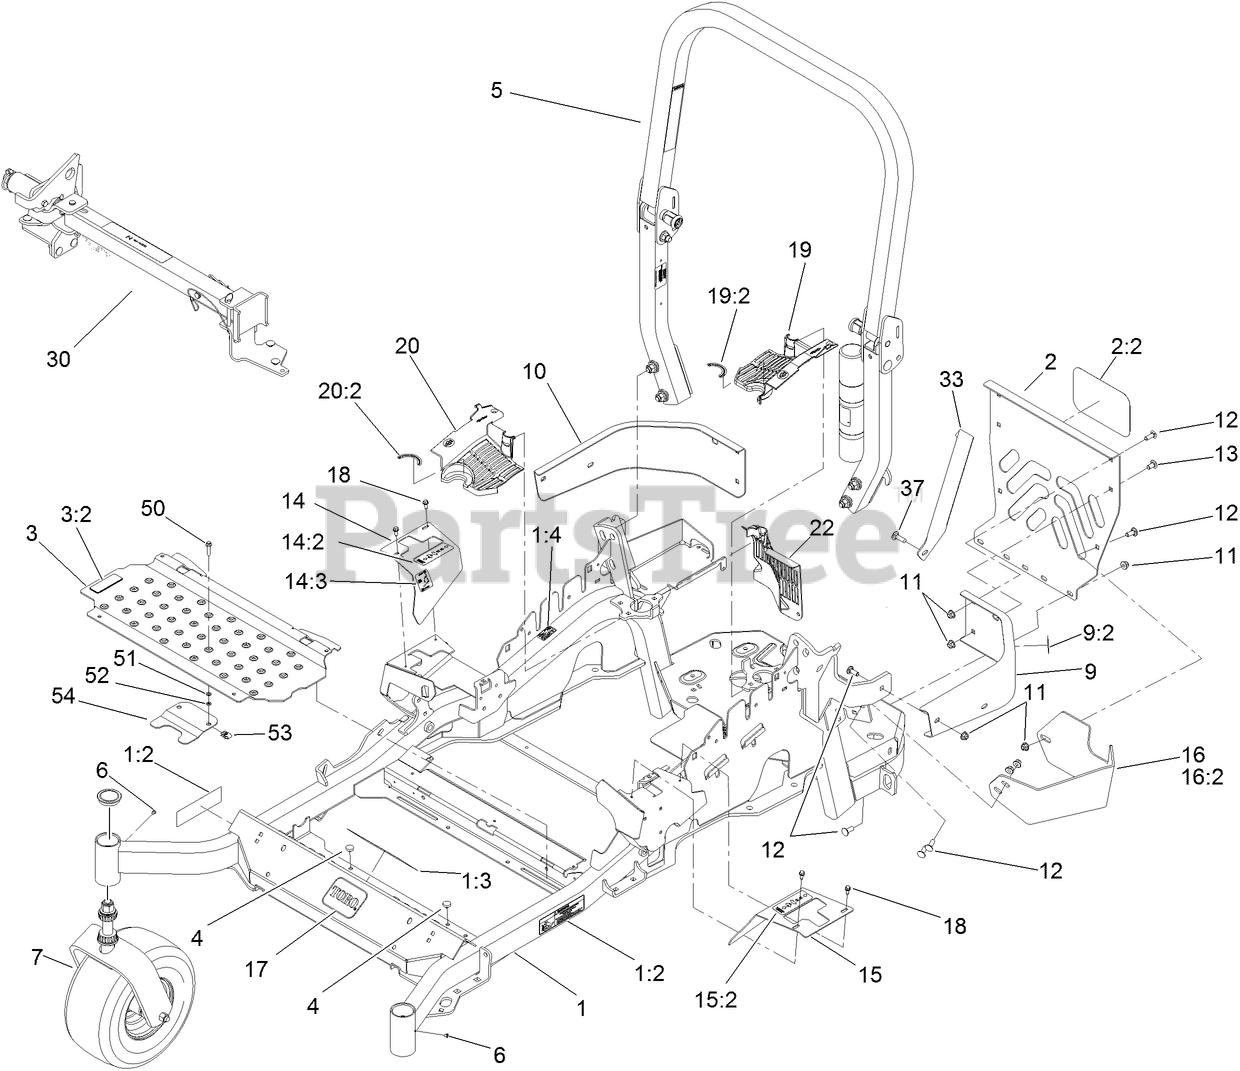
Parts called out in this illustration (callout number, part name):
1	MAIN FRAME ASM
1:2	DECAL-DANGER SLOPE W/ROPS
1:3	DECAL-WARNING
1:4	DECAL-HAZARD, PINCHED FINGER
2	REAR GUARD ASM
2:2	DECAL
3	FLOORPAN ASM
3:2	DECAL-MISSING, COVER
4	BUMPER
5	ROPS ASM
7	Caster Wheel ASM
9	LH REAR BUMPER ASM
9:2	DECAL-WARNING
10	BUMPER-RH
11	NUT-HF, NI
12	SCREW-CARR
13	SCREW-CARR
14	RH MOTION CONTROL COVER ASM
14:2	DECAL-CONTROL, MOTION
14:3	DECAL-PARKING BRAKE
15	LH MOTION CONTROL COVER ASM
15:2	DECAL-CONTROL, MOTION
16	MUFFLER-GUARD, ASM
17	DECAL
18	SCREW-HWH
19	LH HYDRO GUARD ASM
19:2	DECAL-HYDRO OIL
20	RH HYDRO GUARD ASM
20:2	DECAL-HYDRO OIL
22	GUARD-HYDRO, REAR (RH)
30	Z STAND ASM
37	BOLT-CARR
50	SCREW-HHF
51	WASHER-FLAT
52	NUT-RETAINER
54	ADAPTER-CAPTIVE
